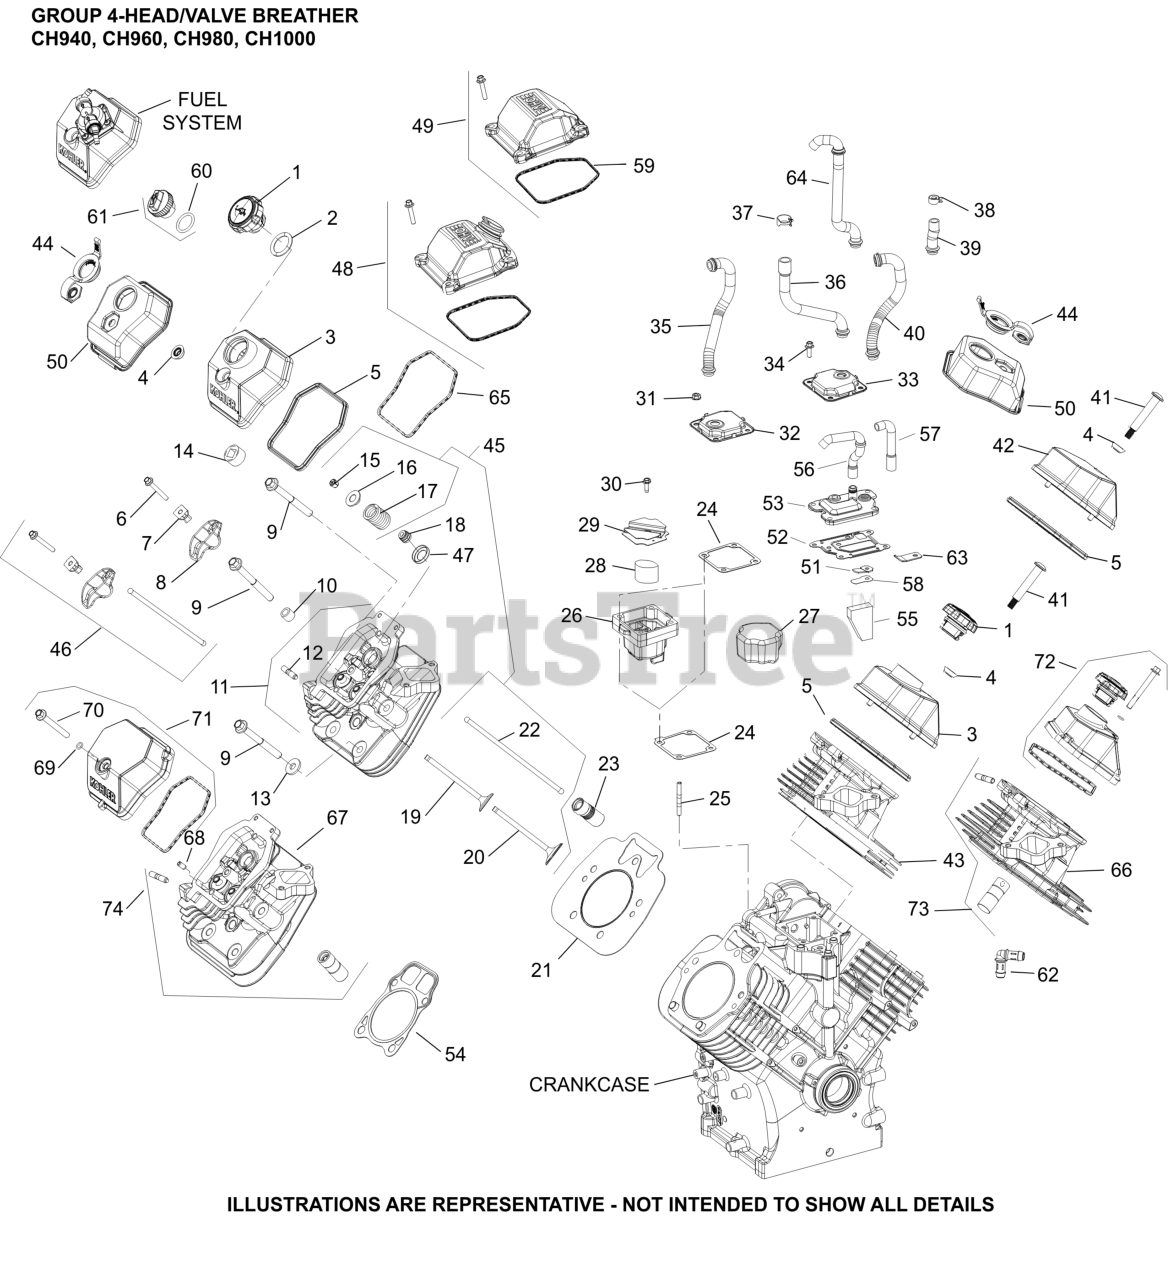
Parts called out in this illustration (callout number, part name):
1	CAP ASSEMBLY
3	KIT, COVER, VALVE (OIL FILL)
4	GROMMET, VALVE COVER SCREW
5	SEAL, VALVE COVER-USE 62 032 20-S
7	PIVOT, ROCKER ARM
8	ARM, ROCKER
9	SCREW, FLG M10X1.5X90
13	WASHER, FLAT 13/32"
14	PLUG, PIPE 3/4 NPTF SQUARE
15	KIT, RETAINER
16	CAP, VALVE SPRING
17	SPRING, VALVE
18	SEAL, VALVE BAND
19	VALVE, EXHAUST
20	VALVE, INTAKE
21	KIT, CYLINDER HEAD GASKET
22	ROD, PUSH
23	LIFTER, VALVE HYDRAULIC-USE 25 351 11-S
24	GASKET, BREATHER
33	KIT, BREATHER ASSEMBLY
34	SCREW, THREAD FORMING
35	HOSE, BREATHER
41	SCREW, SHOULDER
73	KIT, #1 CYLINDER HEAD COMPLETE
74	KIT, #2 CYLINDER HEAD COMPLETE
NI	SCREW, HEX FLANGE
NI	FILTER, BREATHER
